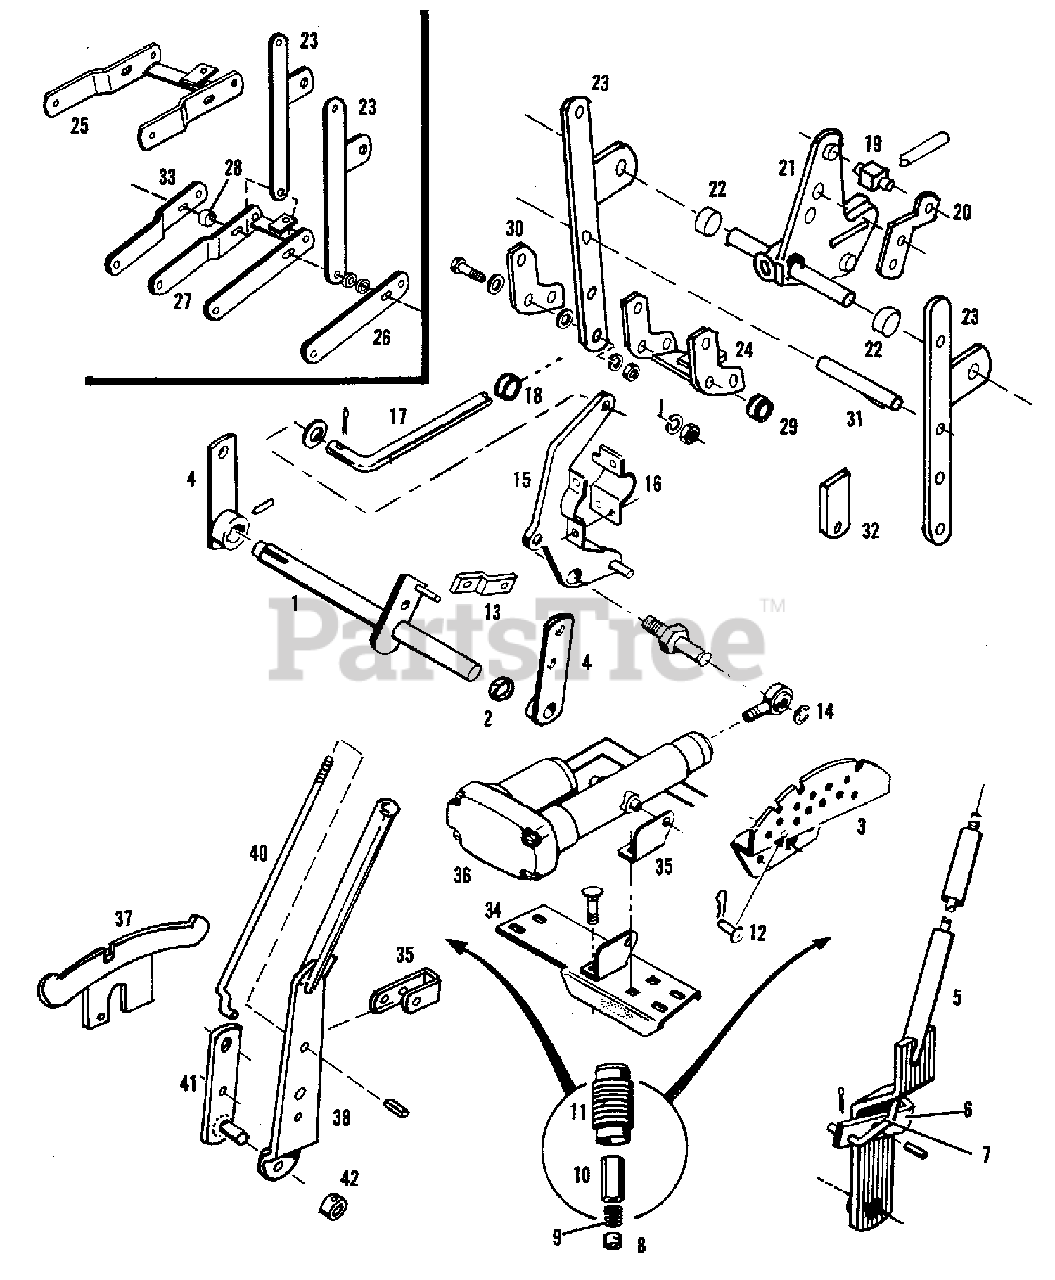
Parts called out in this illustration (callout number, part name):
1	SHAFT ASSEMBLY, Lift
1	KEY, 1/4 x 1/4 x 1
2	COLLAR, Set
2	SETSCREW, 5/16NC x 5/16
3	QUADRANT, Lift Lever
3	CAPSCREW, 3/8NC x 1
3	CAPSCREW, 3/8NC x 3/4
4	LEVER ASSEMBLY, Front Lift
4	LEVER ASSEMBLY, Inner Lift
4	SETSCREW, 5/16NC x 5/16
5	LEVER ASSEMBLY, Lift
6	LATCH, Lift Lever
6	PIN, 3/8 x 1, Spring
6	CAPSCREW, 3/8NC x 1
7	ROD, Latch Lift Lever
8	SPACER, Handle Lever
9	SPRING, Stand
10	BUTTON, Thumb
11	GRIP, Lift Lever
12	PIN, Quick
13	LINK, Rear Lift
14	RING, External Snap (1/2" Shaft)
15	SUPPORT ASSEMBLY, Bellcrank
16	SUPPORT, Bellcrank
16	FITTING, 1/4NF, Straight Lube
16	CAPSCREW, 5/16NC x 1
17	ROD, Lift
17	WASHER, 17/32 x 1-1/4 x 16 Ga.
17	PIN, 1/8 x 1 Cotter
18	NUT, 1/2NC, Jam
20	SUPPORT, Swivel
20	CAPSCREW, 3/8NC x 1-1/4
20	WASHER, 13/32 x 7/8 x 14 GA
21	*&**LEVER ASSEMBLY, Lift
21	*&**BUSHING
21	WASHER, 3/8
22	COLLAR, Set
22	SETSCREW, 5/16NC x 3.8, GR8
23	ARM ASSEMBLY, Drawbar
23	CAPSCREW, 7/16NC x 1
23	LOCKWASHER, 7/16
25	*DRAWBAR ASSEMBLY (Not For Hydrostatic)
26	BAR, Pull (Not For Hydrostatic)(L.H.)
27	**DRAWBAR ASSEMBLY (Hydrostatic Models)
29	SPACER (4 Used On Hydrostatic Models)
29	*&**SPACER (2 Used On Hydrostatic)
29	CAPSCREW, 7/16NC x 1-1/4
29	WASHER, 7/16 (Use As Required)
29	LOCKWASHER, 7/16
29	NUT, 7/16NC
29	CAPSCREW, 7/16NC x 2-1/4
30	PLATE, Draw (Hydrostatic Only)
30	DECAL, Plate (Hydrostatic Only)
31	SPACER (Hydrostatic Only)
31	CAPSCREW, 7/16NC x 1-1/4
31	CAPSCREW, 7/16NC x 3
31	CAPSCREW, 7/16NC x 1-3/4
31	LOCKWASHER, 7/16
31	NUT, 7/16NC
32	STOP, (Hydrostatic Only)
33	DRAWBAR R.H.
34	SUPPORT, Actuator
34	CAPSCREW, 3/8NC x 1
34	WASHER, 12/32 x 7/8 x 14 GA
35	BRACKET, Support
35	BOLT, 3/8NC x 1, Carriage
36	See ELECTRICAL SYSTEM For ACTUATOR & COMPONENTS
37	QUADRANT ASSEMBLY, R.H. Lift
38	LEVER ASSEMBLY, R.H. Lift
39	LATCH, R.H. Lift
39	PIN, 3/8 x 1, Spring
40	ROD, R.H. Lift
40	PIN, 3/32 x 1, Cotter
41	LEVER ASSEMBLY, R.H. Lift
41	CAPSCREW, 1/2NC x 1-1/4
41	LOCKWASHER, 1/2
41	NUT, 1/2NC, Jam
41	CAPSCREW, 3/8NC x 1-1/4
41	LOCKWASHER, 3/8
41	NUT, 3/8NC
41	WASHER, 1/4, Standard
41	WASHER, 1/2, Standard
42	COLLAR, Set
42	SETSCREW, 5/16NC x 1/4
